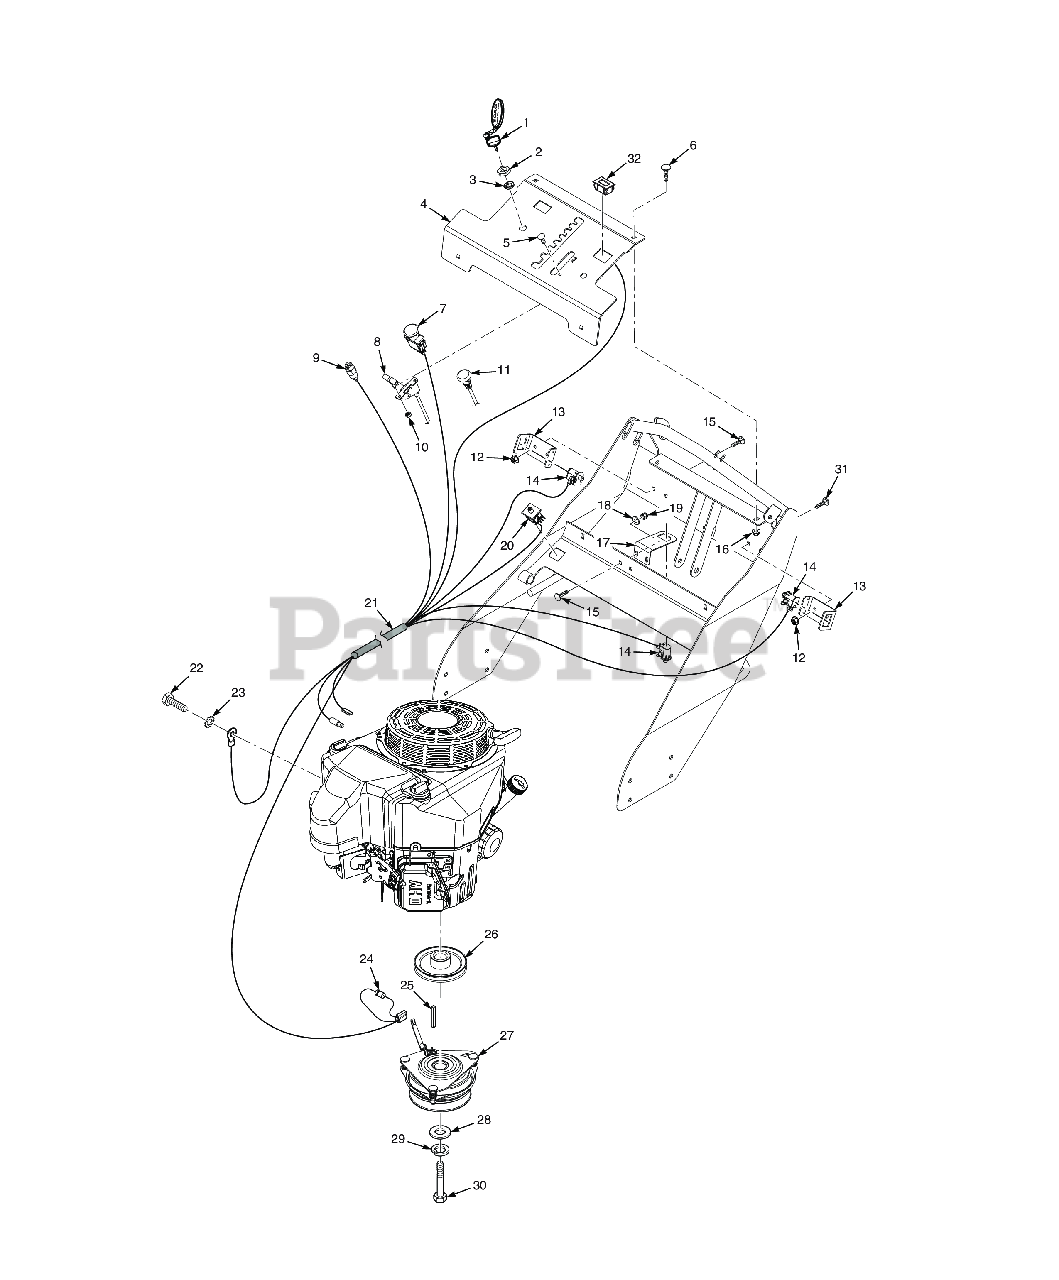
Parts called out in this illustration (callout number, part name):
1	Key, Assembly w/Fob
1	Key w/Shroud Only
2	Nut, 5/8-32 Special
3	LOCK WASHER, 5/8" INTERNAL TOOTH
4	Instrument Panel w/Decal
5	Bolt, Carriage #10-24 x 1/2"
6	Bolt, 5/16-18 x .75 RHSN Carriage
7	Switch, PTO - 10 Amp
8	Throttle Cable
9	KEY SWITCH, MANUAL SRT.(INCL. HWD)
10	Nut, Elastic Stop #10-24
11	Choke Control
12	NUT, 1/4-20 SERRATED FLANGE HEX HEAD
13	Bracket, Operator Presence Switch
14	SWITCH, NEUTRAL INTERLOCK
15	Serr. Fl. Hex Head CPSCR, 1/4-20 x 3/4"
16	Nut, Serrated Flange 5/16-18 (Right Front Engine Mounting, Briggs and Kohler Only)
17	Bracket, Neutral Switch (Manual Start)
18	Flatwasher, 5/16-.375 x .875 x .083 (35BV & 37BV-EFI)
19	HEX, NUT, ELASTIC STOP LOCK, 1/4-20
20	Switch, Double Pole - Plunger
21	Wire Harness
22	Bolt, Hex Hd. M8-1.25 x 14mm
23	Lockwasher, 5/16" Ext. Tooth (Kohler x1)
24	Diode, 600V 6 Amp
25	KEY, 1/4 X 1/4 X 2-1/2"
26	Pulley, 4-1/2" Dia. - 1" Bore
27	Electric Clutch Assembly
28	Flatwasher, 7/16-.469 x 1.75 x .25 (48, 52)
29	Lockwasher, 7/16� Spring
30	Bolt, Hex Head 7/16-20 x 3" w/t Patch
31	Bolt, Carriage, 1/4-20 x 1-1/4"
32	Hour Meter, Inductive
